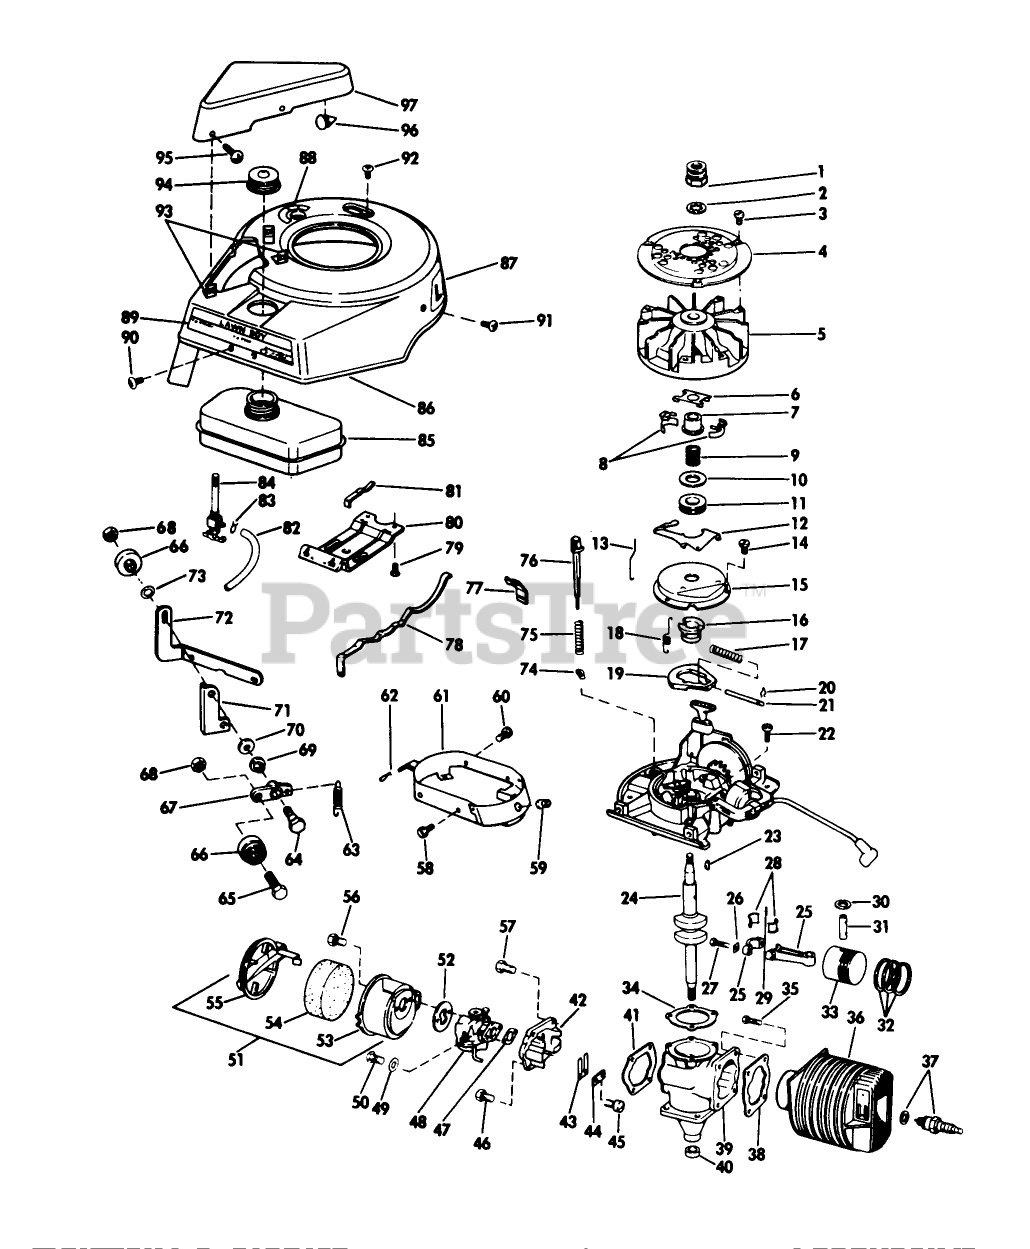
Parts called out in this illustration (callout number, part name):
7	COLLAR S
9	SPRING S
11	THRUST COLLAR S
12	LEVER-GOVERNOR S
14	SCREW S
15	DUST COVER S
16	SPARK ADV. S
17	SPARK ADV. SPRING S
19	FLYWEIGHT S
20	SPARK ADJ. SPRING
21	PIN,SPARK ADV. S
28	LINER ASM
30	RING-RETAINING
34	GASKET S
38	GASKET S
39	Crankcase Reed Plate Assy.
44	PLATE-BACKUP, REED
46	SCREW S
47	GASKET S
54	AIR FIL.ELEM S
56	SCREW S
57	SCREW S
58	SCREW S
59	NUT-CLIP
75	SPRING S
79	SCREW S
82	GAS LINE
83	CLAMP - HOSE S
84	VALVE&SCREEN SM
89	Decal-Instructions
91	SCREW S
